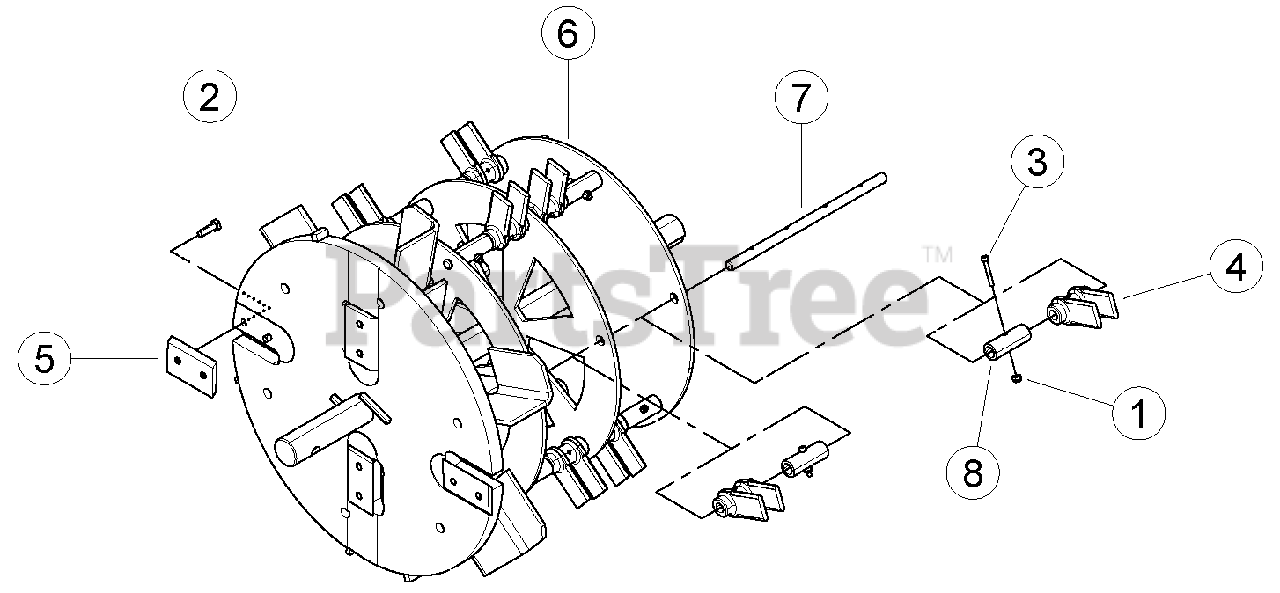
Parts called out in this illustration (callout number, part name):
1	NUT, 10/24 NYLOCK TYPE NM ZP
2	BOLT, 5/16-18 X 1 HEX HD GR8 PATCH ZP
3	CAP SCREW, #10-24 X 1-3/8 SKT HD PL
4	FLAIL, CHIPPER/SHREDDER CAST (REPLACED AND SUPERSEDED. FOR SERVICE ORDER KIT # 77613-00, SHREDDER KNIVES KIT)
5	KIT, CHIPPER BLADE
6	WELDMENT, 5 INCH C/S ROTOR
7	ROTOR FLAIL SHAFT (LARGE C/S)
